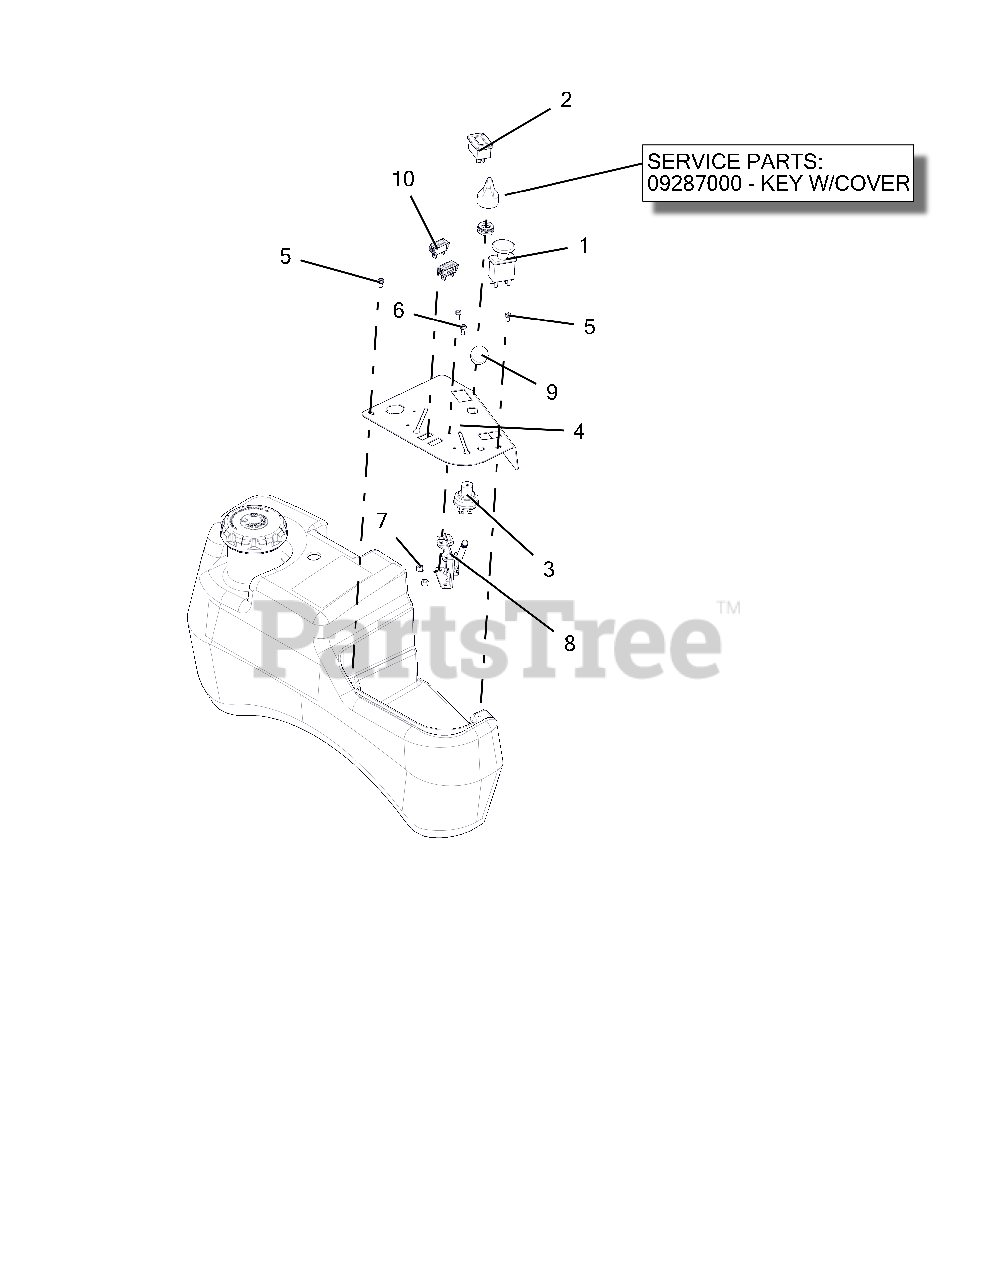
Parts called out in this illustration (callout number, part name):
1	SWITCH, CLUTCH
2	METER, HOUR W/MAINTENANCE
3	SWITCH, IGNITION
4	PANEL, CONTROL - PROTURN 100
5	SCR-MCH 10-24X.38 HWHSTAINLESS
6	@SCR-MCH 10-24X.50 HWH YWZC
7	NUT-LK-NYL #10-24 YWZC
8	CABLE, PRO-CONTROL THROTTLE
9	KNOB, CONTROL BLACK .38-16X.50
10	LIGHT, INDICATOR
11	KEY W/COVER
